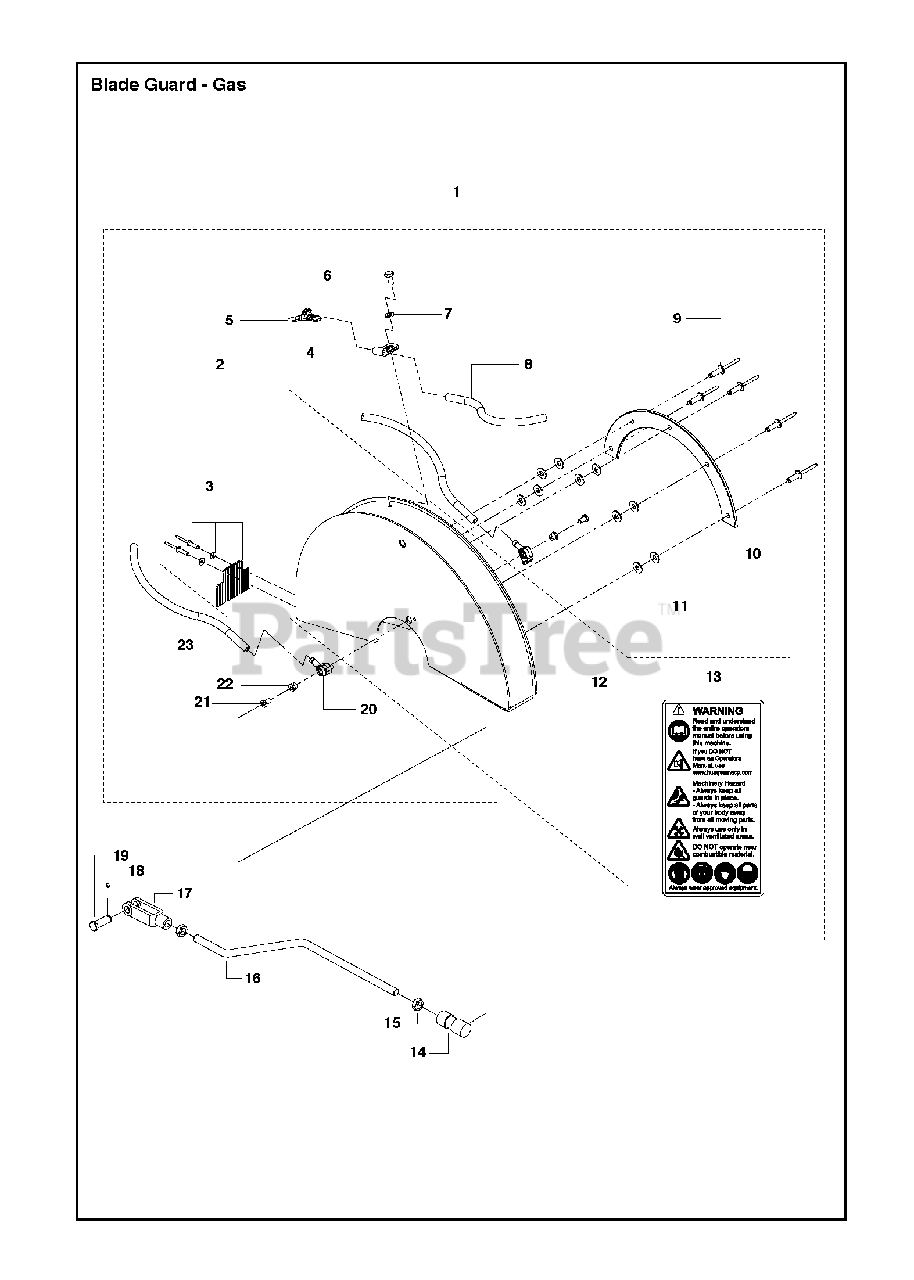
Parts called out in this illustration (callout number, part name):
6	HCS ¼-20 X ½ GR 5 ZD
8	HOSE
11	WASHER 1/4 SAE
14	QUICK DISCONNECT-BODY
18	PIN, COTTER .0937 X .625
21	SCREW ITXSCM
23	HOSE
